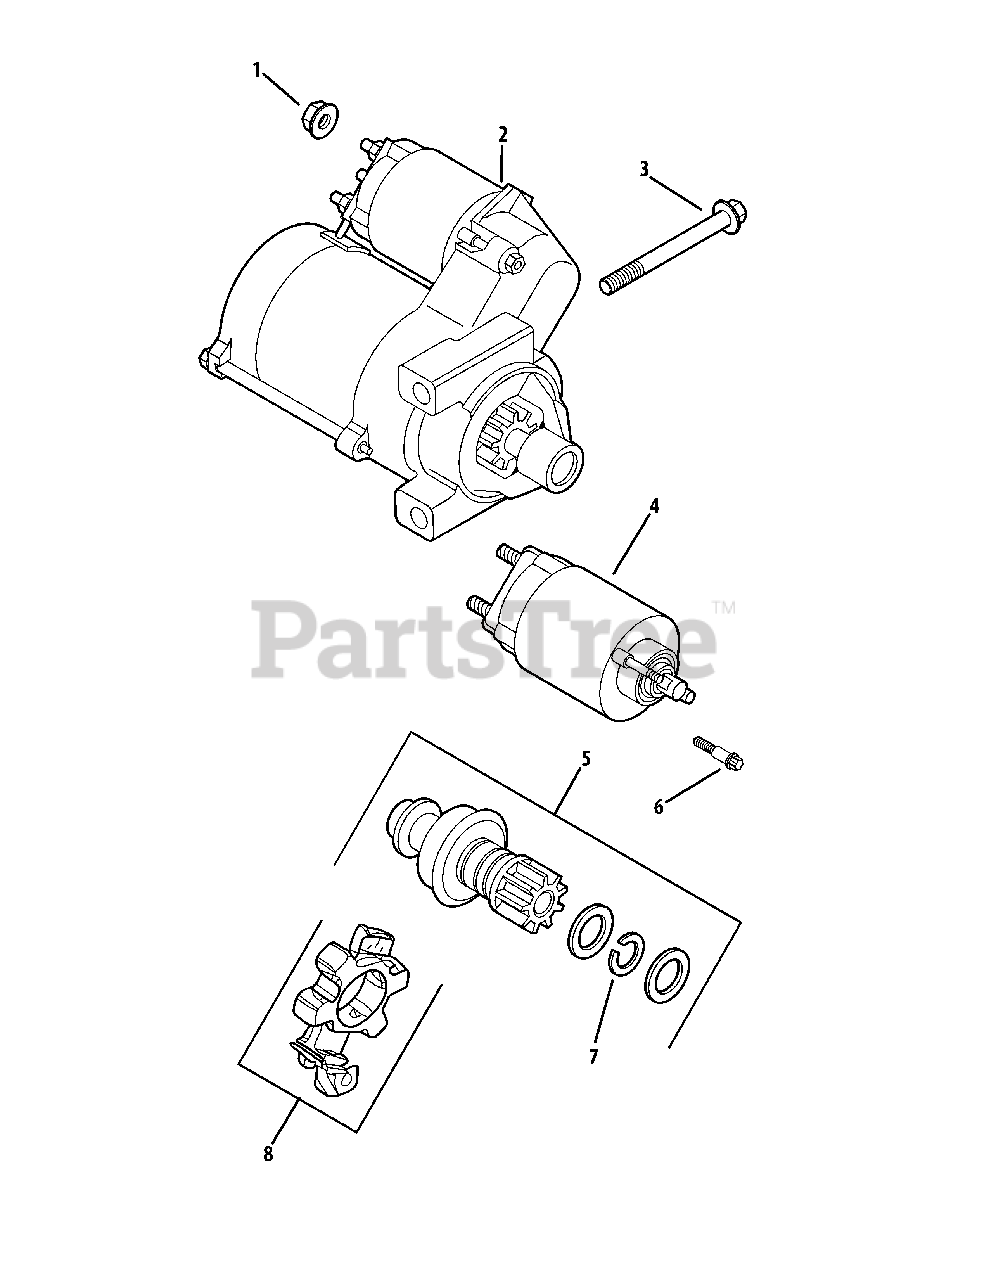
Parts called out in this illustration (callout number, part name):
1	Flange Nut, M8 x 1.25
2	Electric Starter (Solenoid Shift)
3	Flange Screw, M8 x 1.25 x 80
5	Starter Pinion Kit
6	External Torx Head Screw
7	Retaining Ring
8	Brush Holder Kit
